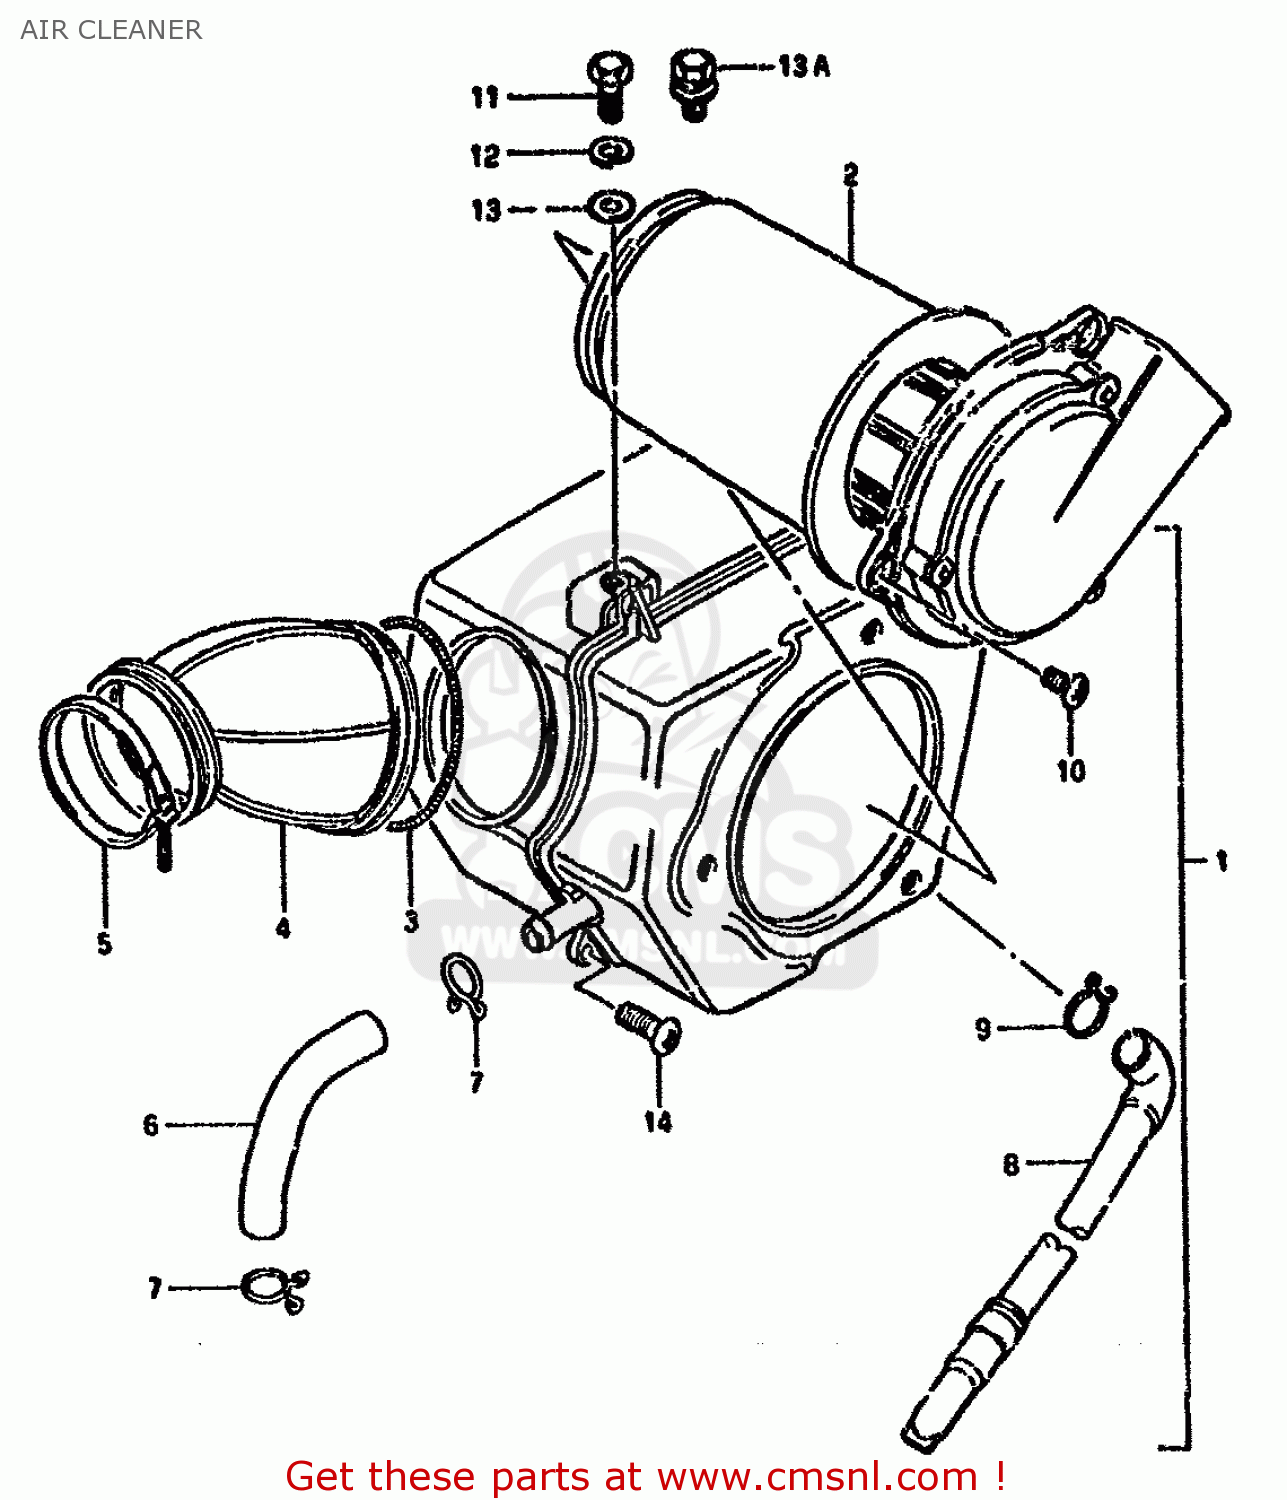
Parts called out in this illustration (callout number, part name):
1	CLEANER ASSEMBLY,AIR
2	FILTER
3	CLAMP,AIR CLEANER SIDE
4	TUBE,OUTLET
5	CLAMP
6	TUBE,BREATHER
7	CLIP,BREATHER TUBE
8	DRAIN TUBE
9	CLIP
10	SCREW
11	BOLT
12	WASHER,LOCK
13	WASHER
13A	BOLT(6X16)
14	SCREW
